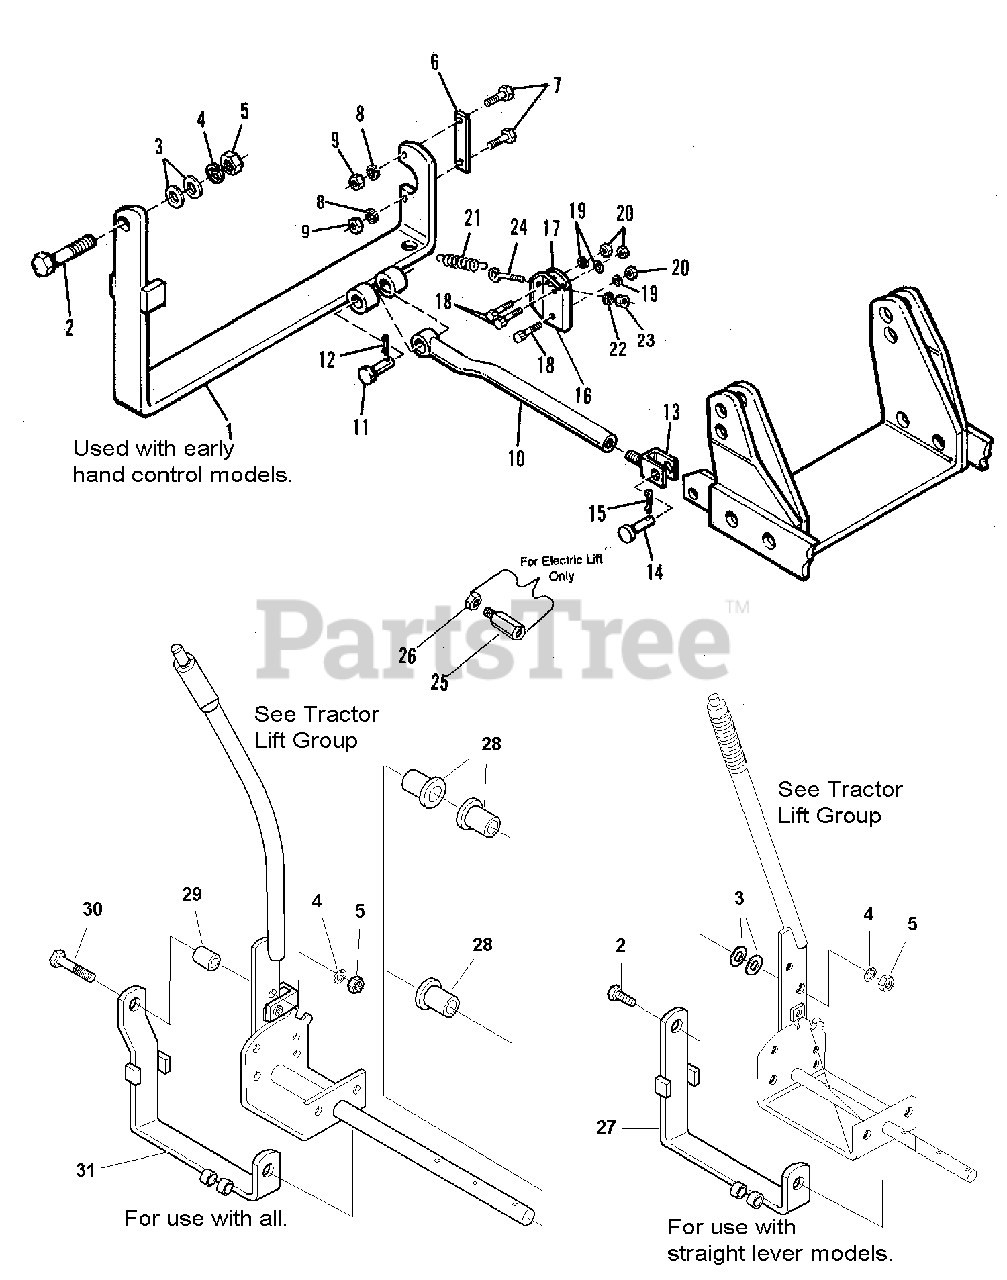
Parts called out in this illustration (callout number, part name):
1	BRACKET, Lifting, Manual
2	CAPSCREW, Hex, 1/2-13 x 1-3/4
3	WASHER, Plain, 1/2
4	LOCKWASHER, 1/2
5	NUT, Hex, 1/2-13
6	PLATE, Anchoring
7	CAPSCREW, Hex, 1/4-20 x 1
8	LOCKWASHER, 1/4
9	NUT, Hex, 1/4-20
11	PIN, Clevis
12	COTTER PIN, 3/32 x 1
13	FORK, Threaded
14	PIN, Clevis, 5/8 x 1-5/8
15	CLIP, Hairpin, 1/8 x 2-9/16
16	BRACKET, Fixation
17	PLATE, Retaining
18	CAPSCREW, Hex, 3/8-16 x 1-1/4
19	LOCKWASHER, 3/8
20	NUT, Hex, 3/8-16
22	LOCKWASHER, 1/4
23	NUT, Hex, 1/4-20
24	EYEBOLT, 1/4-20 x 4
25	ROD, Extension (Electric Lift Only)
26	NUT, Hex, 5/8-11 (Electric Lift Only)
27	BRACKET, (Straight Lift Handle Models)
30	CAPSCREW, Hex Head, 1/2-13 x 2
31	BRACKET, (All Lift Handles)
